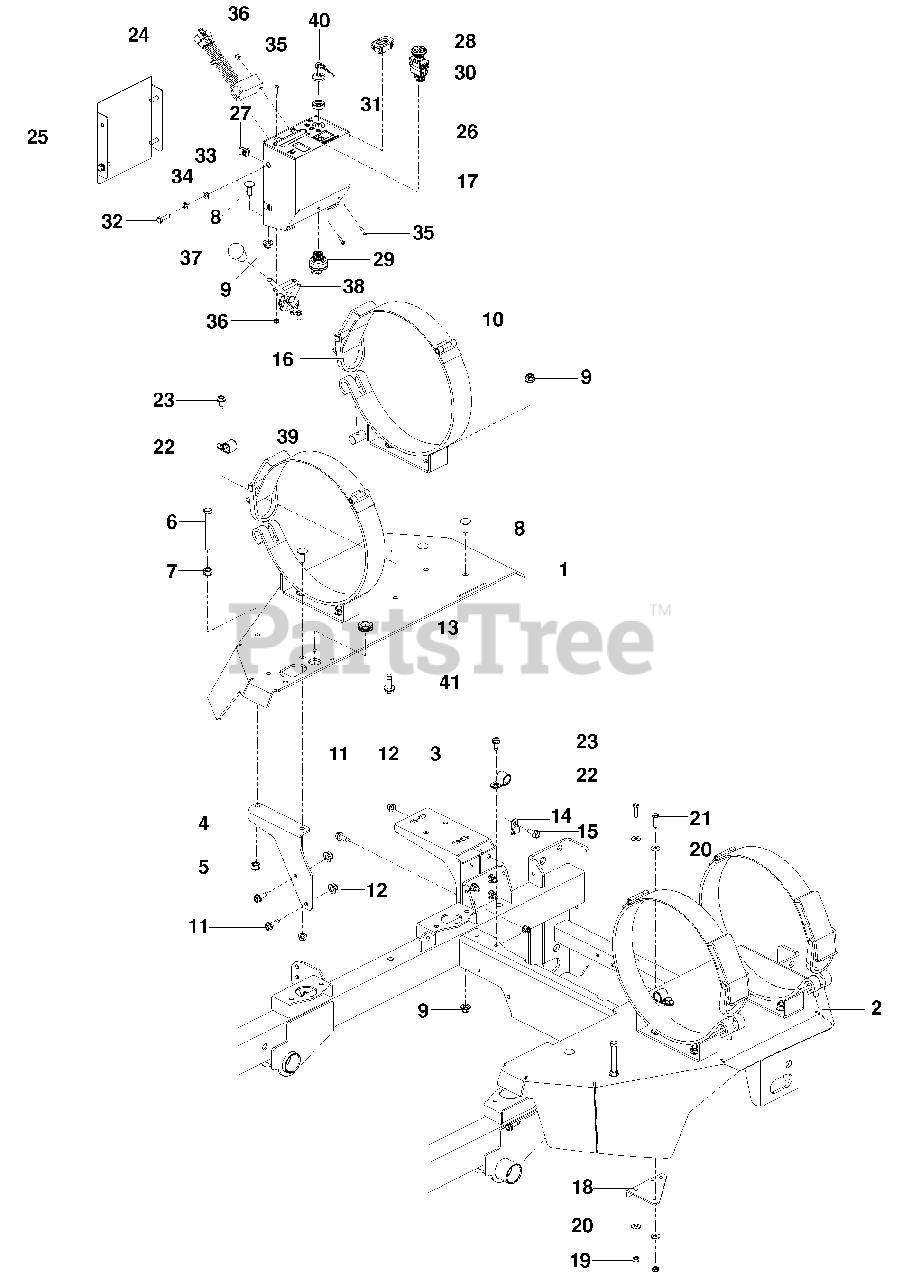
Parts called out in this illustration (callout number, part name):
1	Fender, Lp Rt
2	Bolt 7/16-20 X 1 1/2 Hex Nyl
3	Mount, Tank Rr
4	Support, Lp Fender Rt
5	Nut 3/8-16 Hex Cntrlk
6	Hcs 3/8-16 X 3 1/2
7	Nut 3/8-16 Hex Whizlk
8	Bolt 3/8-16 X 1 Rd Hd
9	Nut 3/8-16 Hex Flg Nyloc
10	Bracket, Lp Tank
11	Bolt 5/16-18 X 1 Thd Frm
12	Nut 5/16-18 Hex Flg Nyloc
13	Grommet, Fuel Line
14	Clamp, Double Tube
15	Screw 5/16-18 X 3/4 Hex Flg
16	Toggle Assy
18	Bracket, Regulator
19	Nut 1/4-20 Hex Nyloc
20	Washer 1/4 Flat
21	Bolt 1/4-20 X 1 Hex Hd
23	Bolt 5/16-18 X 3/4 Thd Frm
24	Timer, Seat
25	Cover, Lp Dash
26	Decal, Lp Control
27	Retainer, U Type
28	Hour Meter
29	Switch, Ignition
30	Switch, Pto 10 Amp
31	Cap, Ignition Switch Nut
32	Bolt 5/16-18 X 1 Hex Hd
33	Washer 5/16 Sae Flat
34	Washer 5/16 Slw
35	Screw 10-24 X 3/4 Skt Hd
36	Nut 10-24 Hex Nyloc
38	Cable, Throttle
39	Nut, Toggle
41	Screw 3/8-16 X 1 Hex Hd
